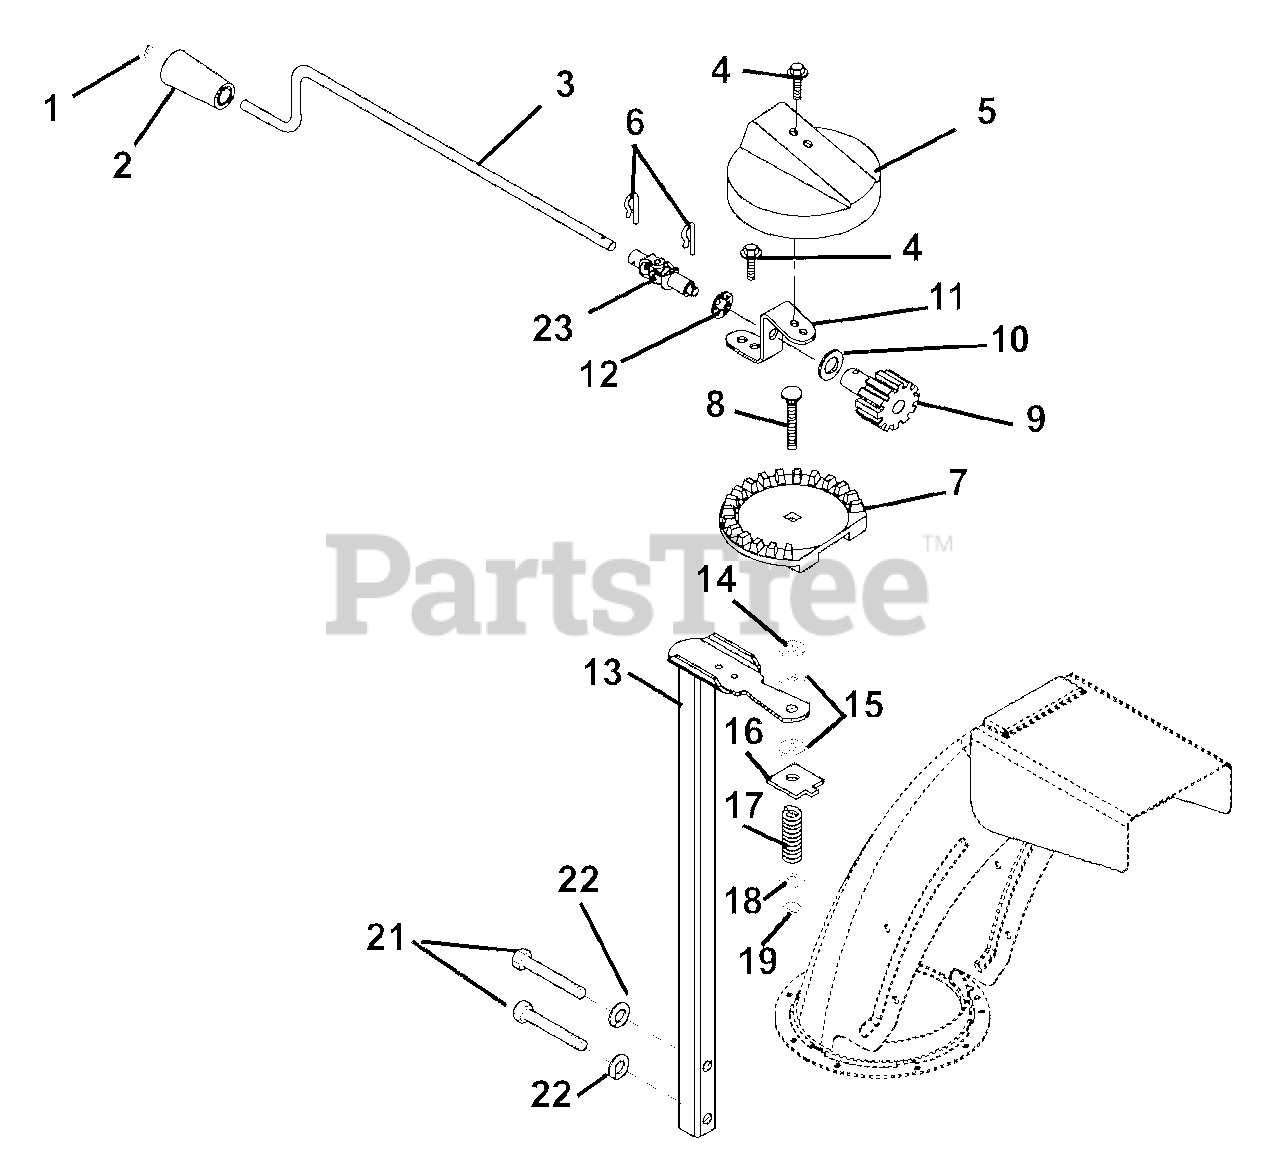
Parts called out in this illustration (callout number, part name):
1	CAP, 3/8 ROD YWZC
2	KNOB, CHUTE CRANK
3	CRANK, CHUTE
4	@SCR-TAP .25-20X.50 HWH TR YWZ
5	GEAR COVER
6	PIN, SPRING CLIP
7	CHUTE GEAR
8	@BLT-RDHDSQNK .38-16X2.50 G5YZ
9	PINION GEAR W/BRACKET
10	WSHR-FL-STL .630X1.005X.062 YZ
11	BRACKET-GEAR
12	PUSHNUT .625
13	PEDESTAL, CHUTE SUPPORT
14	WSHR-FL-STL .380X1.50X.062 YWZ
15	FRICTION WASHER
16	FRICTION PLATE
17	SG-COMP .187X.56X1.62
18	@WSHR-FL-STL.406X.812X.065 YWZ
19	@NUT-LK-CTR .38-16 YWZC
21	@BLT-HEX .38-16X1.75 GR5 YWZC
22	@WSHR-LK .38X.094 REG YWZC
23	ASS'Y, UNIVERSAL-W/PIN END
